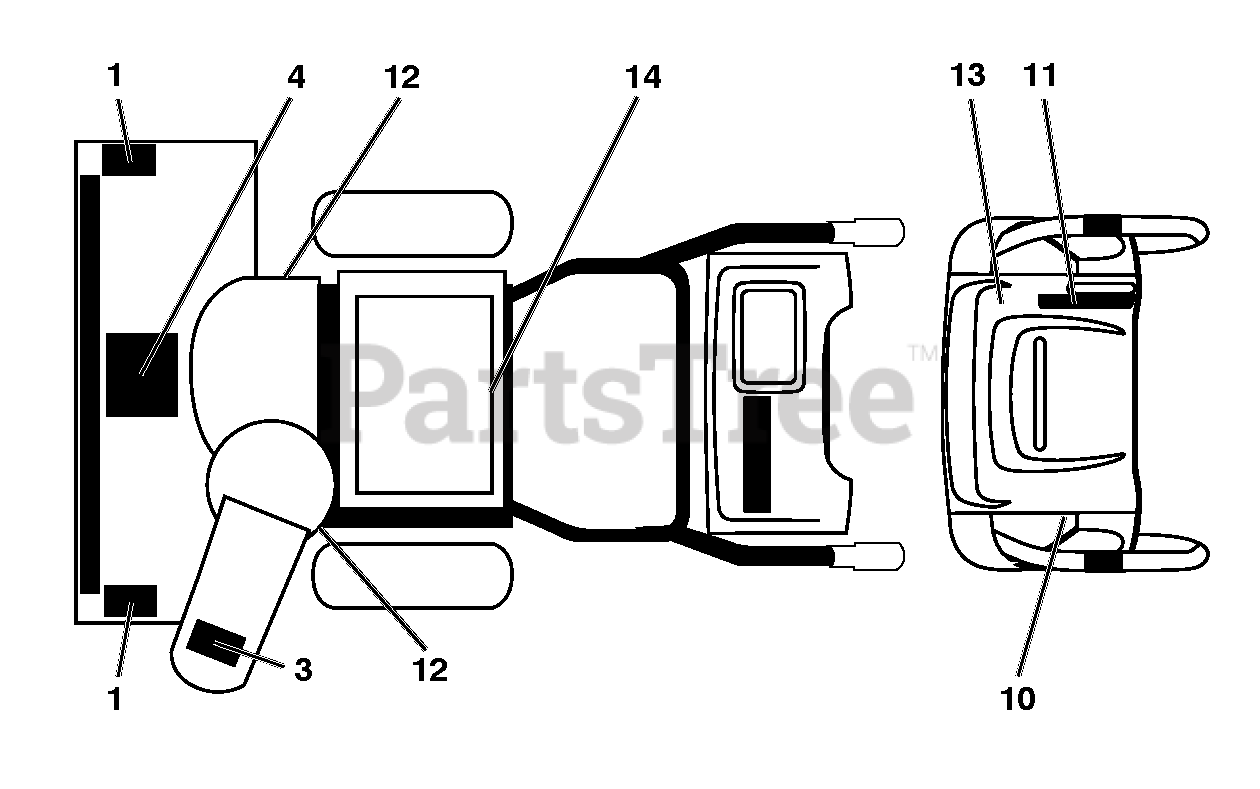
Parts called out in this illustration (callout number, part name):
1	DECAL.AUGER.SAFETY.
3	DECAL.CHUTE.SAFETY.
4	DECAL.AUGER."
10	DECAL.CONS.LH.REMOTE.INST.GRY
11	DECAL.CONS.RH.INST.GRY
12	DECAL.BELT.GUARD.
13	DECAL.CONSOLE.HAND.WARMER
14	DECAL.FENDER
